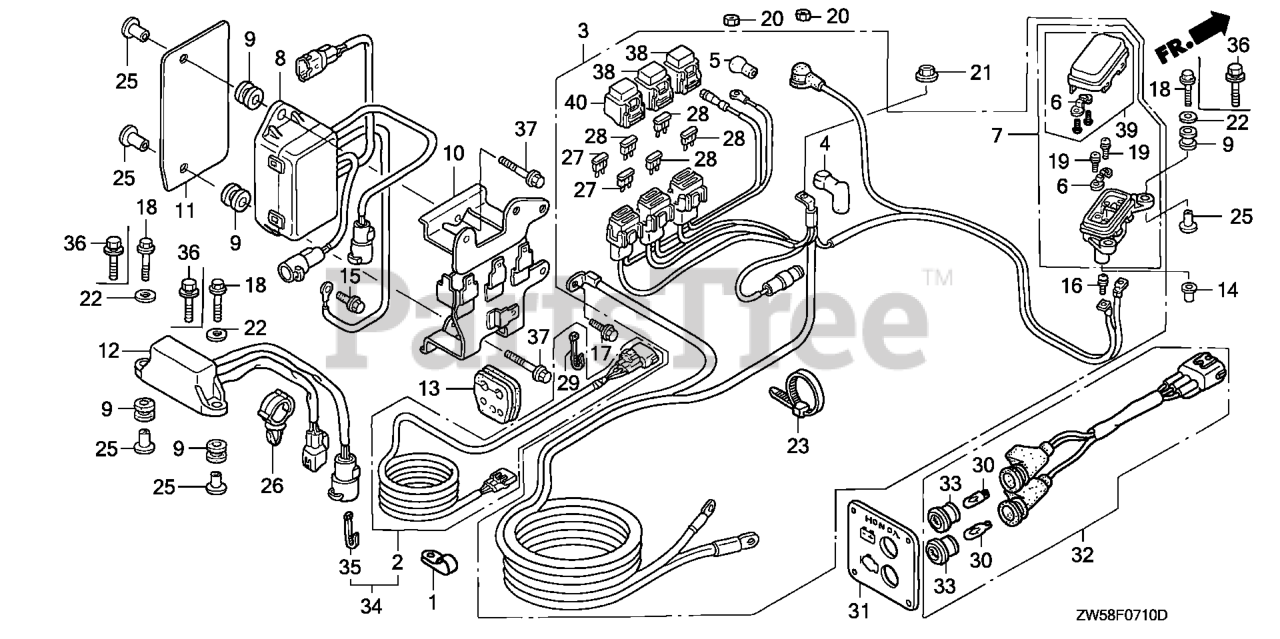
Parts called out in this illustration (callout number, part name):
1	CLAMP F, CABLE
2	WIRE ASSY., INDICATOR (3P/3P) (ANALOG)
3	CABLE ASSY., STARTER
4	COVER, STARTER TERMINAL
5	COVER A, MAGNETIC SWITCH
6	FUSE (90A)
7	BOX ASSY., FUSE (90A)
8	RELAY ASSY., POWER TILT
9	GROMMET, RELAY
10	BRACKET, RELAY
11	INSULATOR, RELAY
12	RELAY ASSY., MAIN
13	GROMMET, CASE (LOWER) (A)
14	GROMMET A, LEG SHIELD
15	BOLT, FLANGE (6X12) (CT200)
16	BOLT-WASHER (5X9)
17	BOLT, FLANGE (8X18)
18	BOLT, FLANGE (6X25)
19	SCREW-WASHER (5X10)
20	NUT, HEX. (6MM)
21	NUT-WASHER (8MM)
22	WASHER, PLAIN (6MM)
23	BAND, WIRE HARNESS
25	COLLAR, MODULE IGNITION CONTROL CASE (CDI)
26	CLIP, WIRE HARNESS *NH1L* (BLACK)
27	FUSE, BLADE (10A)
28	FUSE, BLADE (30A)
29	TIE, CABLE (NATURAL 2.4X92) Use up to Frame SN 1300359.
37	BOLT, FLANGE (6X25)
38	COVER ASSY., FUSE (30A)
39	COVER ASSY., FUSE (90A)
40	COVER ASSY., FUSE (10A)
